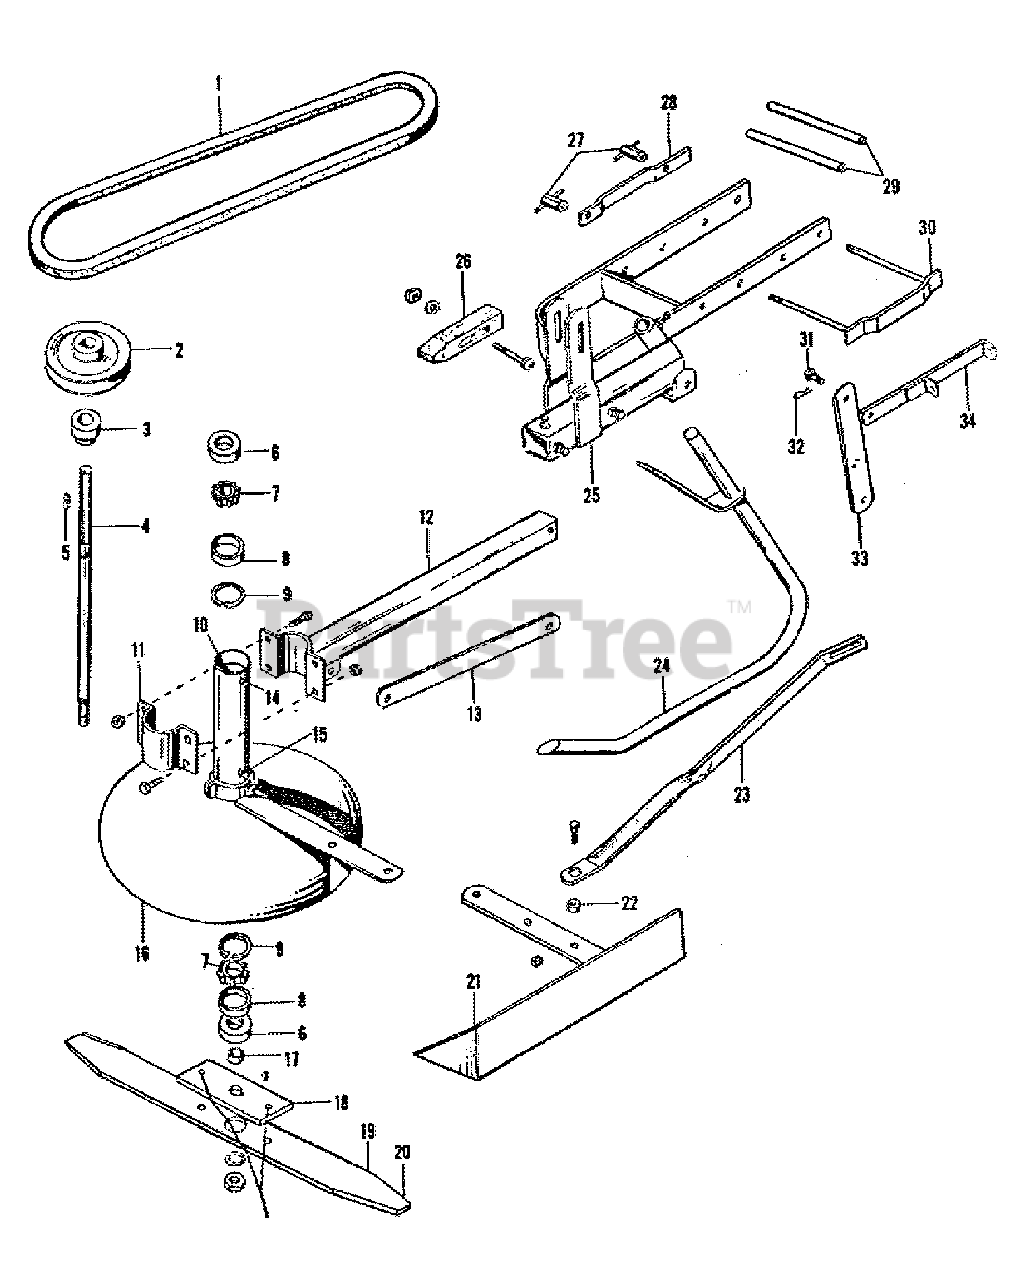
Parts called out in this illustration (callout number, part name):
1	BELT, V, 50"
2	PULLEY, Arbor
3	COLLAR, Arbor
5	KEY, Arbor Pulley
6	SEAL, Oil
7	CONE, Roller Bearing
8	CUP, Roller Bearing
9	RING, Retaining
10	BEARING HOUSING, Arbor
11	HOUSING CLAMP, Arbor
12	CLAMP TUBE ASSEMBLY, Bearing Housing
13	CLUTCH LEVER LINK, Bearing
14	GREASE FITTING, #1792 Alemite
15	GREASE FITTING, #1641 Alemite
16	DEFLECTOR ASSEMBLY
17	SPACER, Arbor
18	FLANGE, Arbor
19	BLADE, Knife (20")
20	BLADE, Knife (26")
21	GUARD ASSEMBLY, Fence
22	SPACER, Deflector Brace
23	BRACE, Deflector
24	SHOE ASSEMBLY, Gauge
25	ARM ASSEMBLY, Push
26	SHOE, Brake
27	NUT, Wing, Complete
28	SIDE PLATE, Hitch
29	SPACER
30	-
31	-
32	-
33	-
34	-
